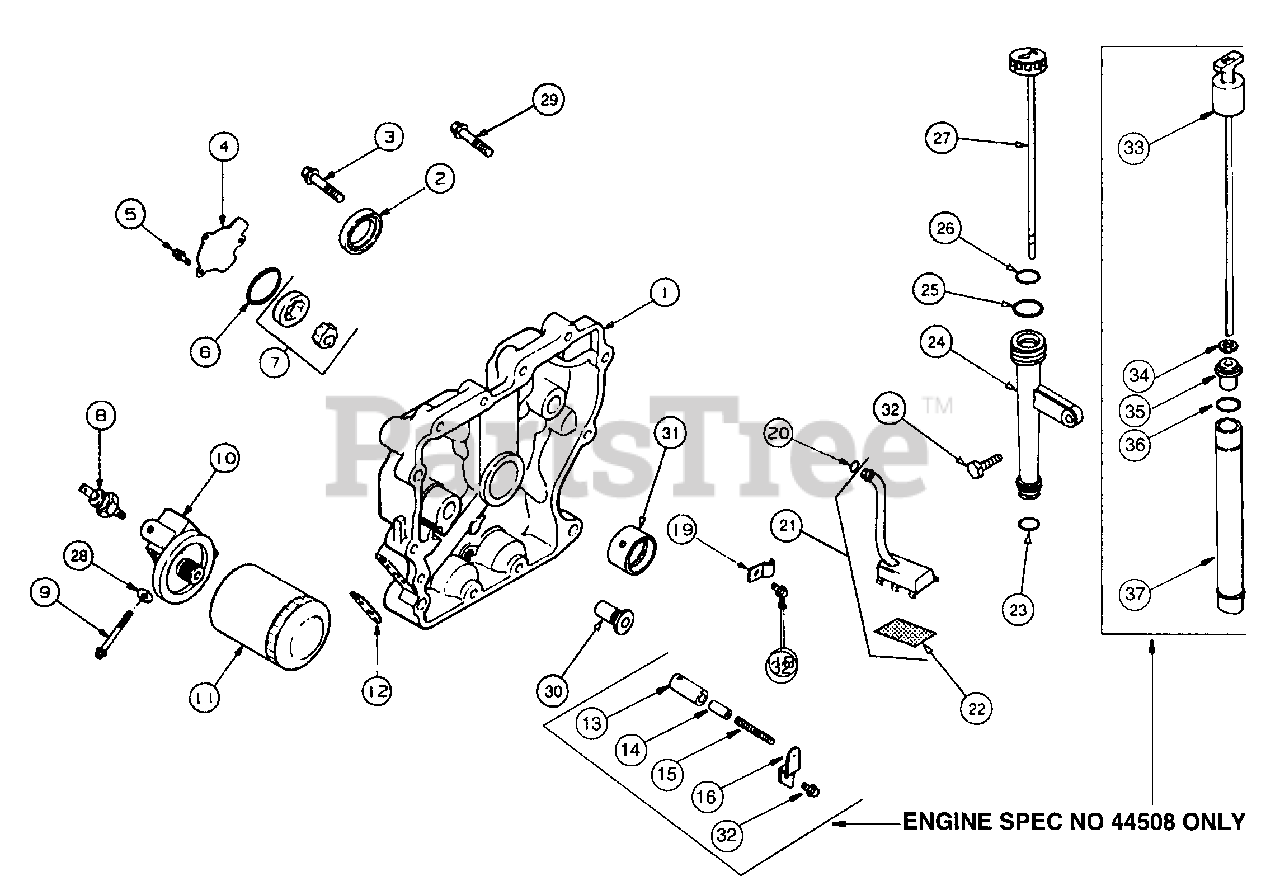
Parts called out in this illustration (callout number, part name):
1	Plate Assembly, Closure
2	Seal, Oil (PTO End)
3	Screw, Closure Plate, M8 x 1.25 x 45
4	Cover, Oil Pump
5	Screw, Oil Pump Cover, M5 x .8 x 16
6	O-Ring, Oil Pump
7	Pump Assembly, Oil
8	Switch, Oil Pressure
9	Screw, Oil Filter Adapt, M6 x 1 x 55
10	Adapter, Oil Filter
11	Filter, Oil
12	Gasket, Oil Filter Adapter
13	Body, Oil Pump Relief Valve
14	Piston, Oil Pump Relief Valve
15	Spring, Oil Pump Relief Valve
16	Bracket, Oil Pump Relief Valve
19	Clip Oil Tube
20	O-Ring, Oil Pick-Up
21	Kit, Oil Pick-Up
22	Pick-up, Oil Screen
23	O-Ring, Lower Oil Fill Tube
24	Tube, Oil Fill
25	O-Ring, Upper Oil Fill Tube
26	O-Ring, Dipstick Cap
27	Cap/Dipstick, Oil Fill
28	Washer, Plain, 1/4
29	Screw, Hex Flange M8 x 1.25 x 45
30	Valve, Oil Pressure Relief
31	Bearing, Thrust
32	Screw, Hex Flange M5 x .8 x 16
33	Dipstick Assembly
34	Washer, Plain, 5/16
35	Seal, Rubber
36	O-Ring, Lower Oil Fill Tube
37	Tube Oil Fill
